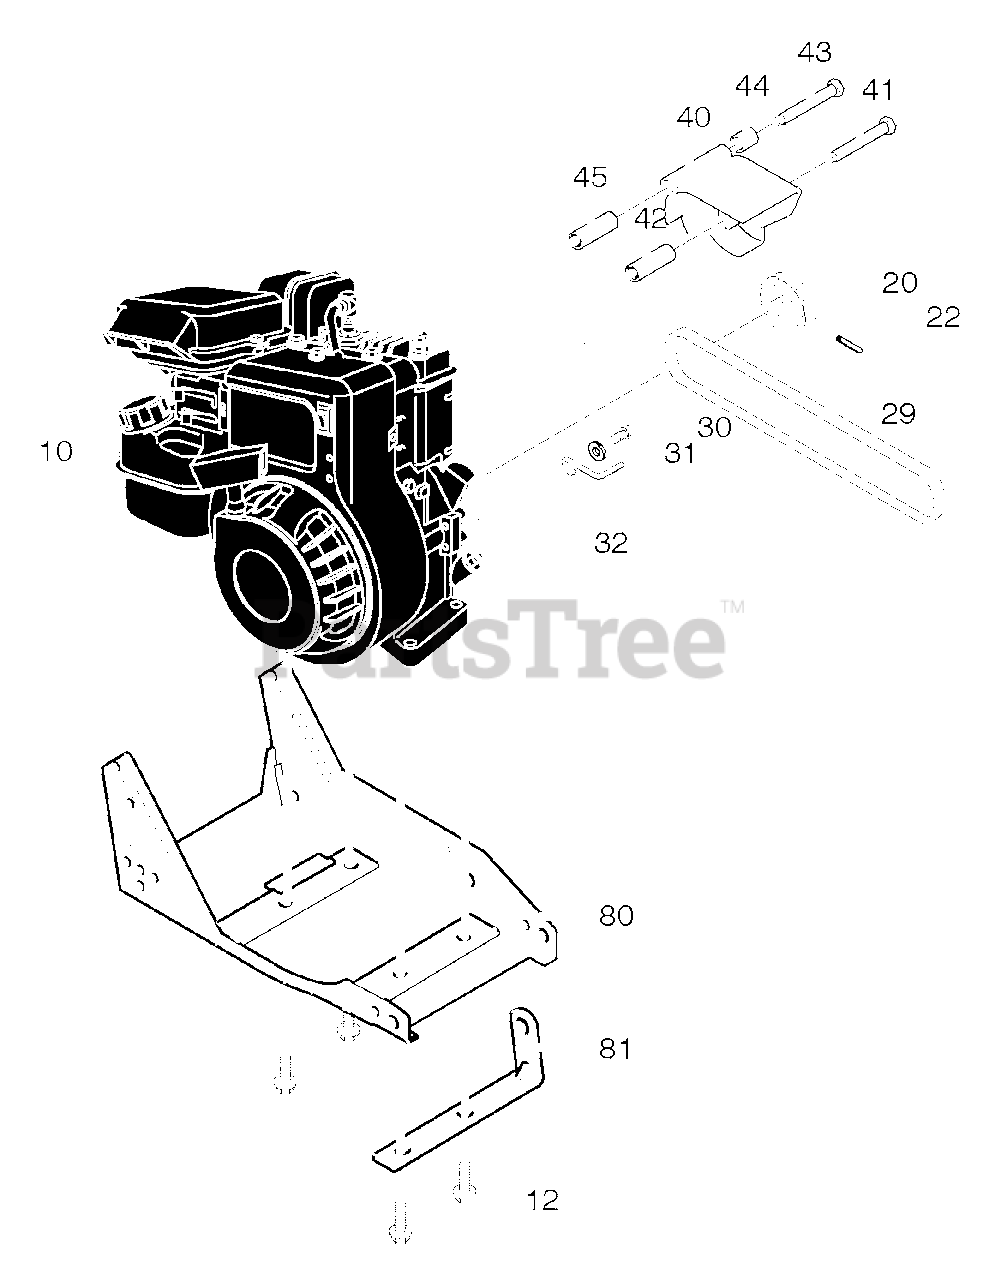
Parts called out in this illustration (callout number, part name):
12	Screw, 3/8-16 x 1.50
22	Screw, Set
29	Belt, 4L 32.60"
30	Screw 5/16-24x1.00
31	Flat washer
32	Guide, Belt
40	Cover, Engine Pulley
41	Screw, 5/16-24 x 3.00
42	Spacer, Sleeve
43	Screw, 5/16-24 x 3.75
45	Spacer, Sleeve
80	Assembly, Frame
